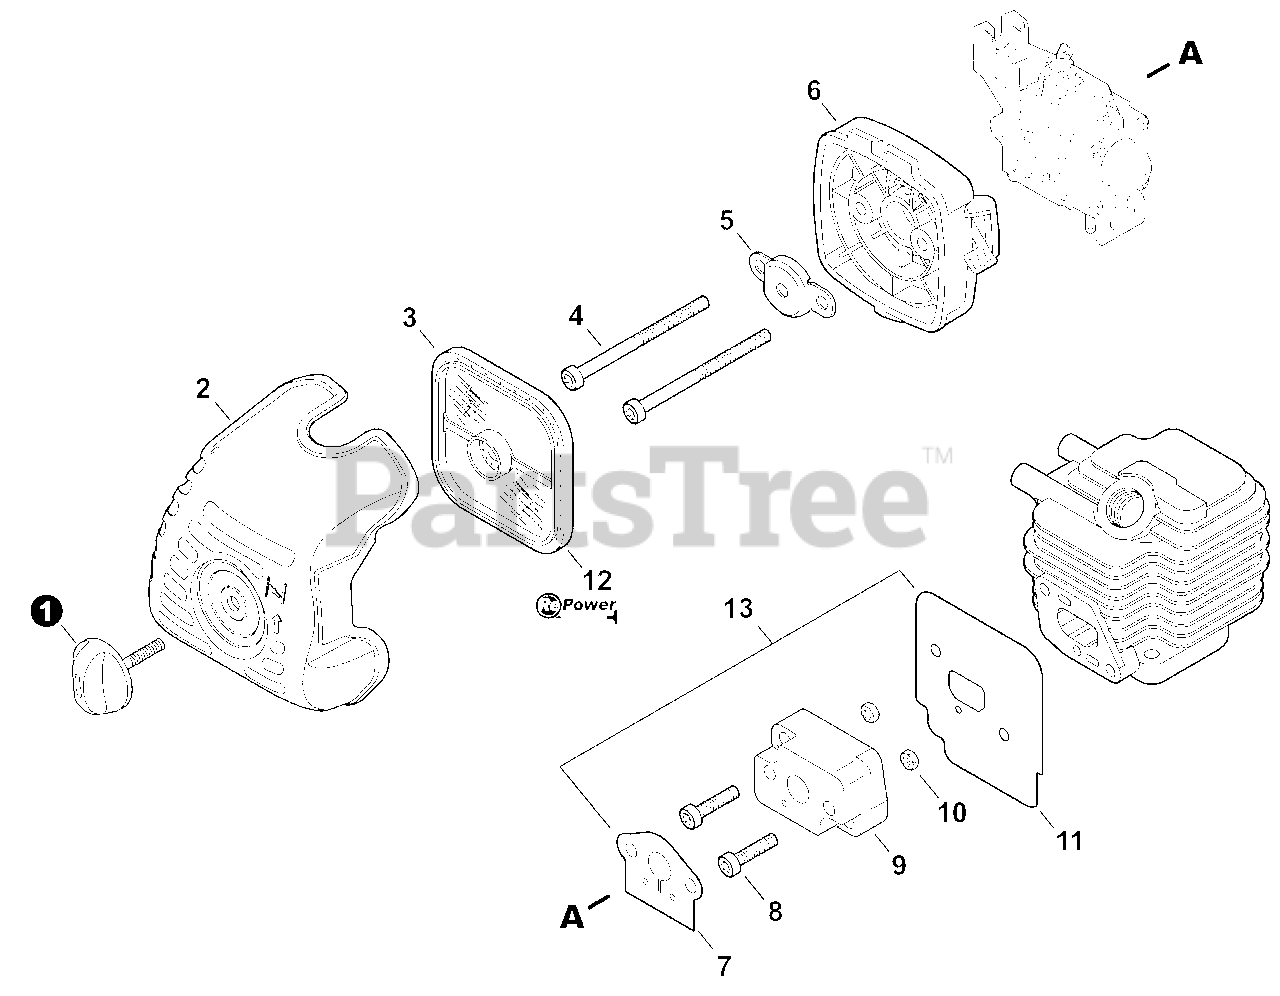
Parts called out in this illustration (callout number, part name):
1	THUMBSCREW
2	COVER, AIR FILTER
3	FILTER, AIR - DOUBLE LAYER
4	BOLT, TORX 5×65
5	PLATE, PREVENT
6	CASE ASSY, AIR FILTER
7	GASKET, INTAKE
8	BOLT, TORX 5×20
9	INSULATOR, INTAKE
10	NUT M5
11	HEAT SHIELD, INTAKE
12	TUNE-UP KIT - REPOWER
13	GASKET KIT: ENGINE, INTAKE, EXHAUST
